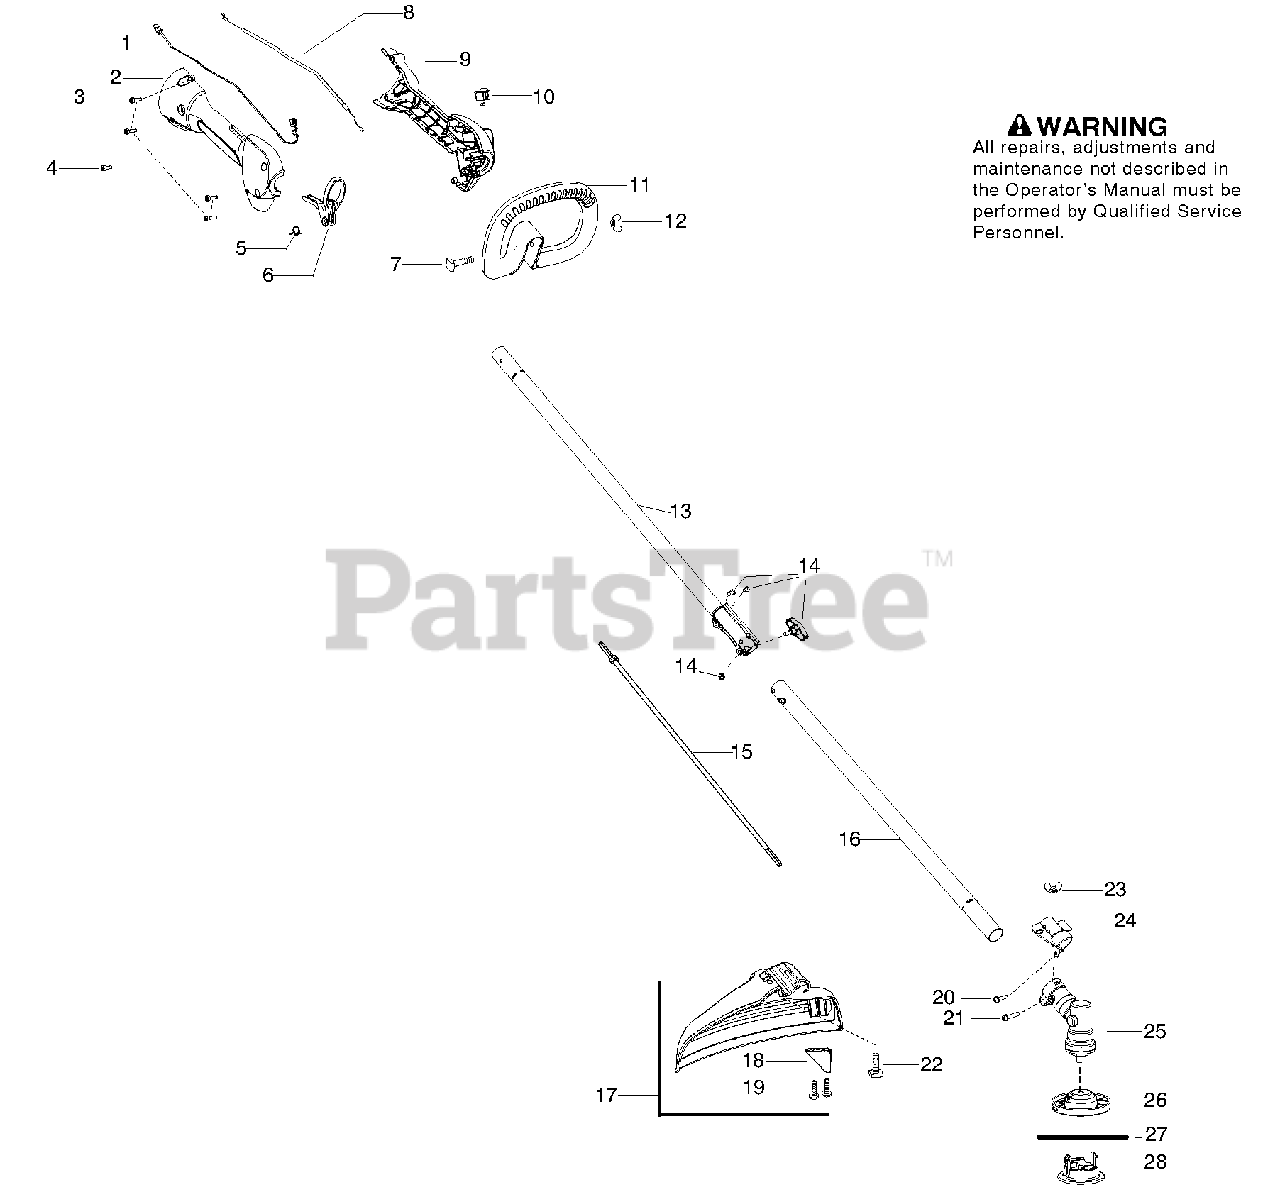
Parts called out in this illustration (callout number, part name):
1	Assy-Switch Wire
2	Housing-Throttle (RH)
3	Screw M4
4	Screw 10-14 x 1/2
5	Spring-Trigger
6	Kit - Trigger
7	Bolt - 1/4-20 x 2
8	Assy - Throttle Cable
9	Housing-Throttle (LH)
10	Kit-Switch
11	Assy - Handle Assist
12	Wingnut - 1/4-20
13	Kit-Driveshaft Upper
14	Kit - Knob / Screw
15	Flexshaft
16	Kit-Driveshaft Lower
17	Kit-Shield
18	Limiter-Line
19	Screw - 10-14 x 3/4
20	Screw - 8-16 x .593
21	Screw - 12-24 x .960
22	Bolt - 1/4-20 x 1-1/4
23	Wingnut - 1/4-20
24	Bracket - Shield
25	Assy - Gearbox 1"
26	Assy - Fixed Line Head
27	Accy - Line .115 - (12 pcs )
28	Cap - Fixed Line
